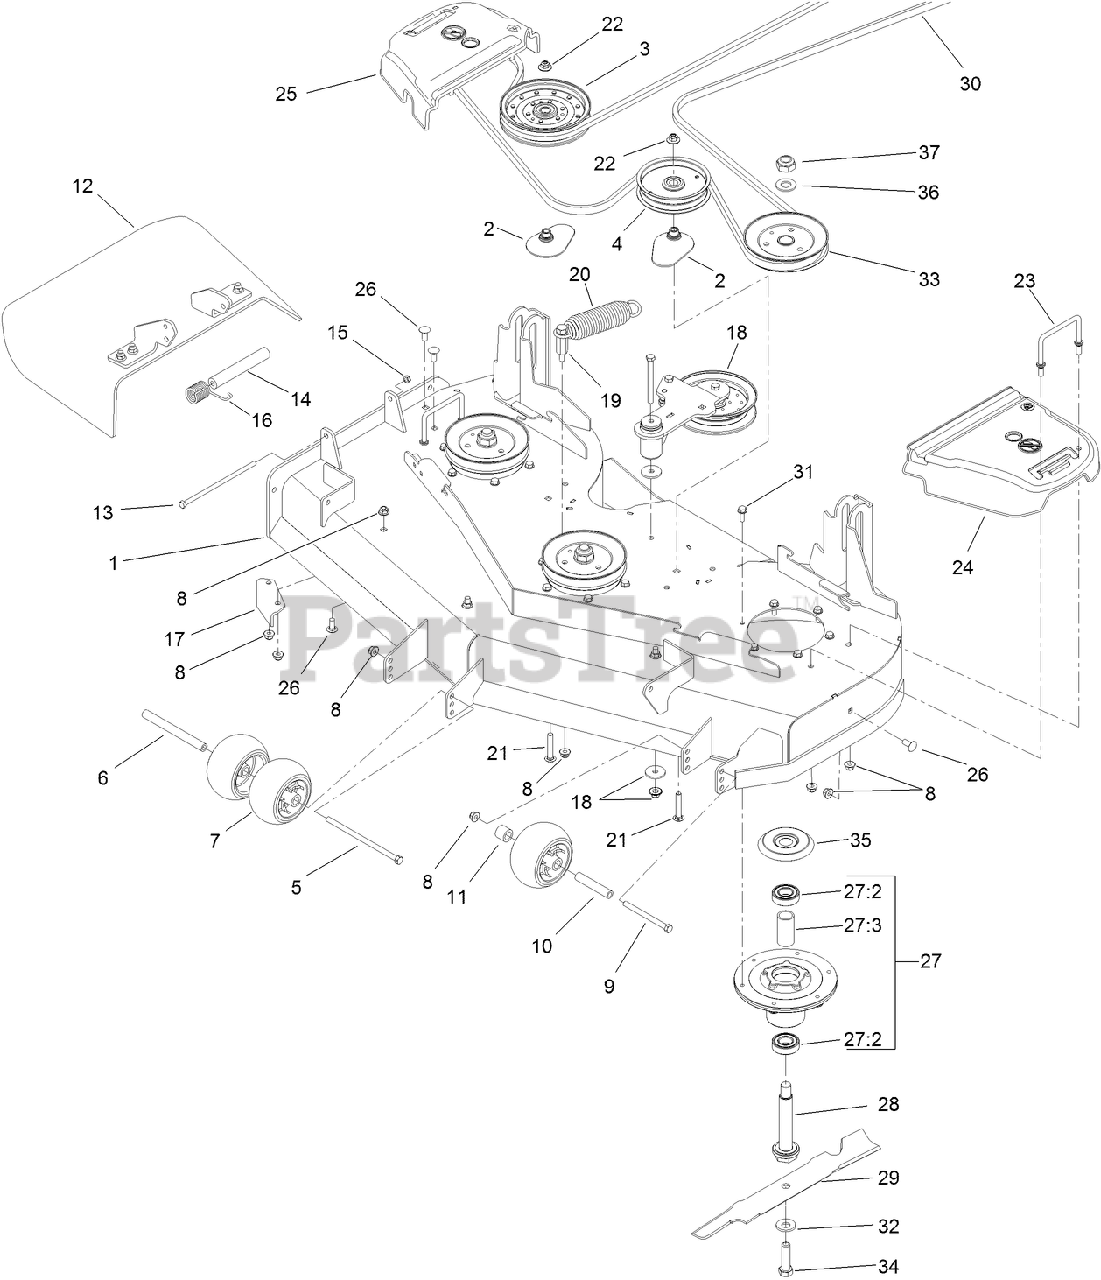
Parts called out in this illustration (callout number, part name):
1	DECK ASM
2	SPACER-PULLEY
3	PULLEY-IDLER, FLAT
4	PULLEY-IDLER, FLAT
5	SCREW-HH
6	SPACER-WHEEL
7	ROLLER-SCALP, ANTI
8	NUT-HF, NI
9	SCREW-HH
10	TUBE-SPANNER
11	TUBE-SPACER
12	DEFLECTOR ASM
13	SCREW-HH
14	SPACER
15	NUT-LOCK, NI
16	SPRING-TORSION
17	BAFFLE-DISCHARGE
18	IDLER ARM ASM
19	ANCHOR-SPRING, TALL
20	SPRING-EXTENSION
21	BOLT-CARR, SHORT NECK
22	NUT-FLANGE, NI
23	WIREFORM-COVER
24	COVER-BELT, LH
25	COVER-BELT, RH
26	SCREW-CARR
27	SPINDLE ASM
27:2	BEARING-BALL
27:3	SPACER-BEARING
28	SPINDLE-SHAFT
29	BLADE-HI FLO, 16.50 INCH
30	BELT-V
31	SCREW-TAPTITE
32	WASHER-BELLEVILLE
33	PULLEY-B SECTION
34	SCREW-BLADE
35	SHIELD-BEARING
36	WASHER
37	NUT-LOCK, NI
